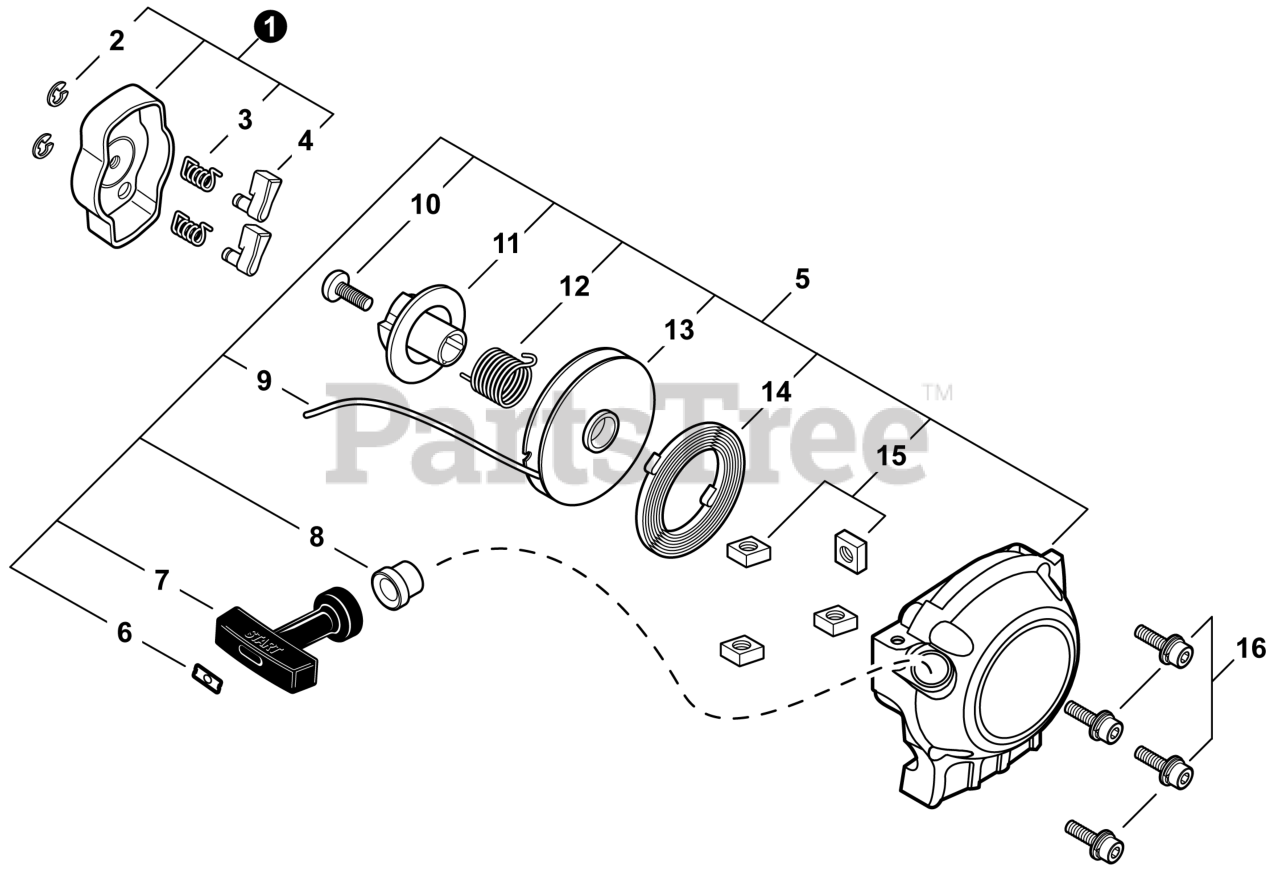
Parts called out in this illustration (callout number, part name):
1	PAWL ASSY, STARTER
2	E-RING 4
3	SPRING, RETURN
4	PAWL, STARTER
5	STARTER ASSY, RECOIL
6	RETAINER, ROPE
7	GRIP, STARTER
8	GUIDE, ROPE
9	ROPE, STARTER 3x700
10	SCREW 5
11	PLATE, CAM
12	SPRING, TORSION
13	REEL, ROPE
14	SPRING, RECOIL
15	NUT - 5 - SQUARE
16	BOLT 4x16
